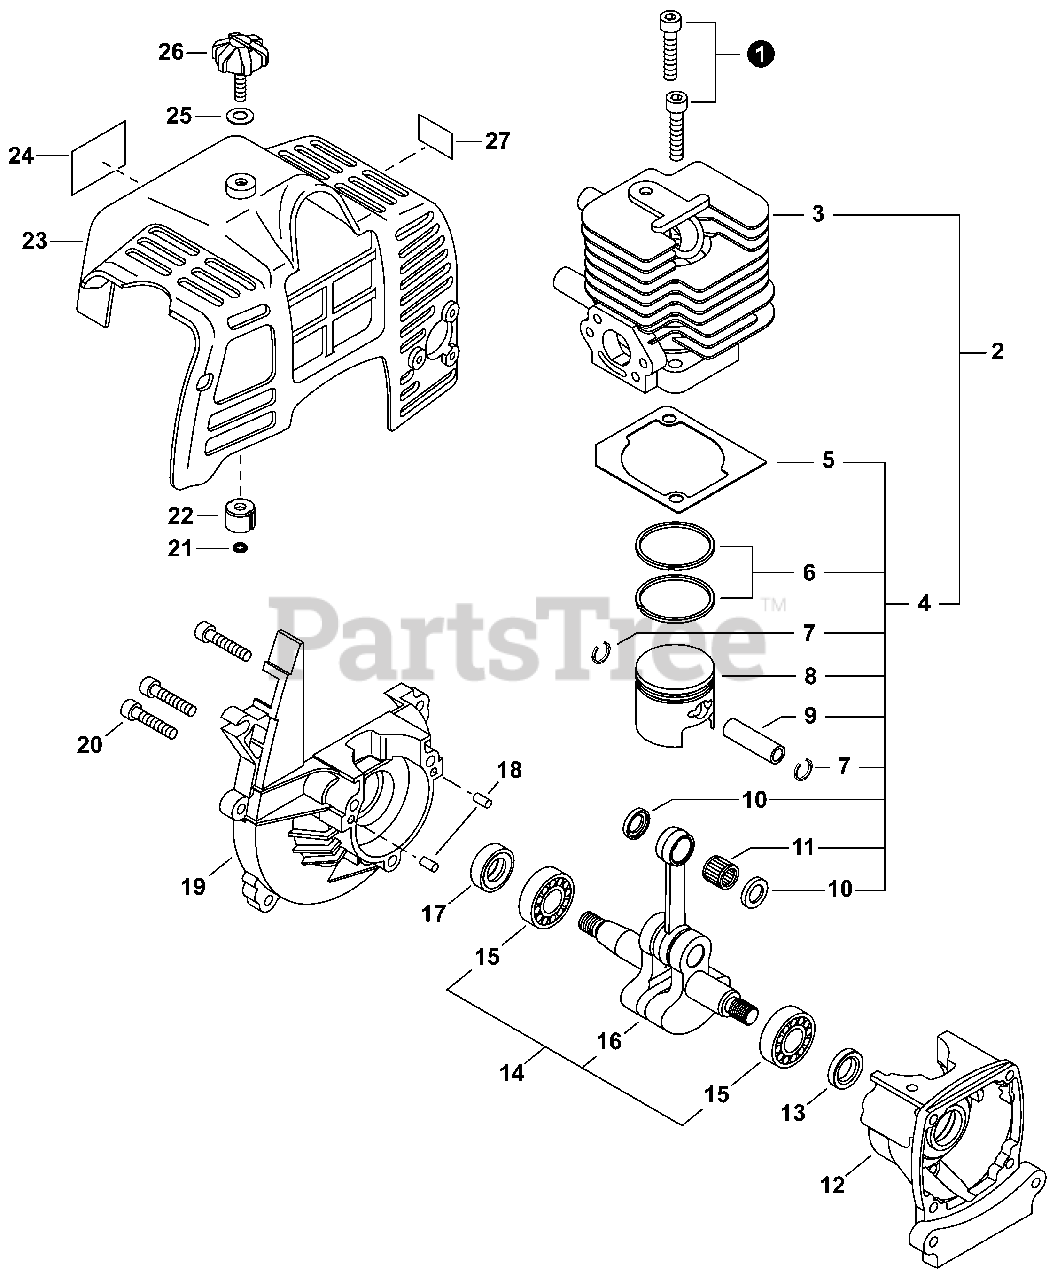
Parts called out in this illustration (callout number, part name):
1	BOLT 5x25
2	REPAIR KIT, ENGINE
3	CYLINDER
4	PISTON KIT
5	GASKET, CYLINDER
6	RING, PISTON
7	RING, SNAP
9	PIN, PISTON 8
10	WASHER, THRUST 8
11	BEARING, NEEDLE 8
12	CRANKCASE S
13	SEAL, OIL 12
14	CRANKSHAFT ASSY
15	BEARING, BALL 6001
16	CRANKSHAFT
17	SEAL, OIL 12
18	PIN, LOCATING 4x8
19	CRANKCASE M
20	BOLT 5x25
22	INSULATOR 5 MM
23	COVER, ENGINE
24	LABEL - MODEL C230
25	WASHER, CONE M6
26	THUMBSCREW
27	LABEL - CAUTION - HOT
